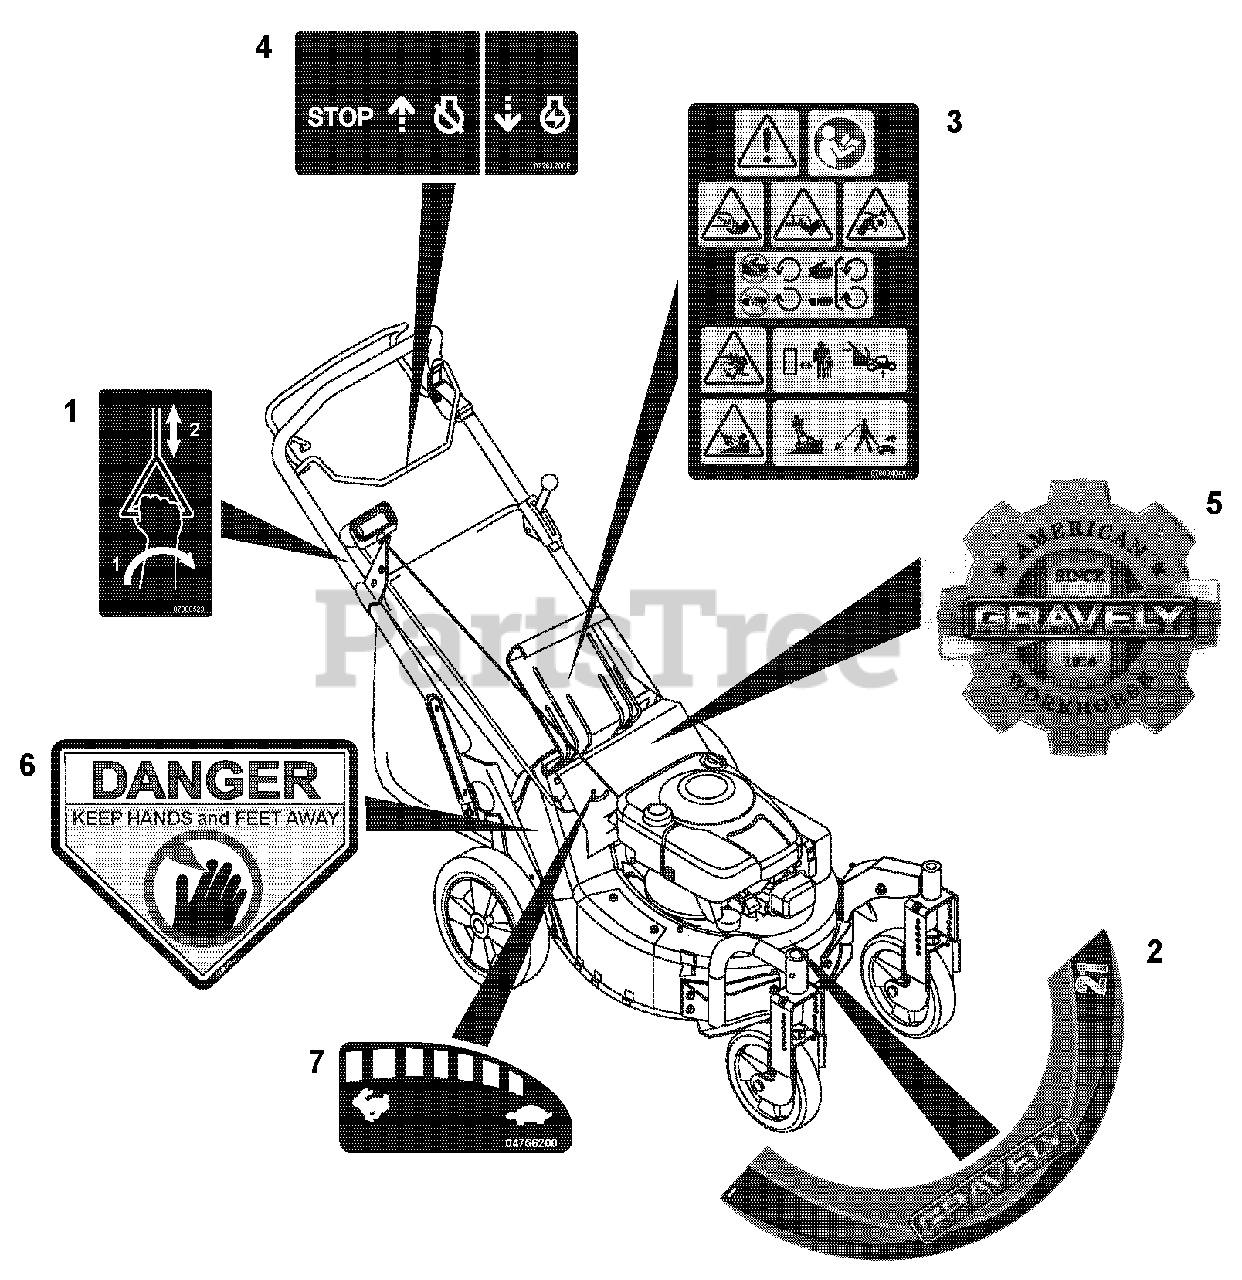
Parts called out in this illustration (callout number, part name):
1	Decal, Speed Select Rod (911196, 197)
2	Decal, Gravely Deck
3	Decal, Main Safety
4	Decal, Engine Control
5	Decal, Gravely Heritage Small
6	Decal, Danger
7	Decal, Speed Select (911196, 197)
